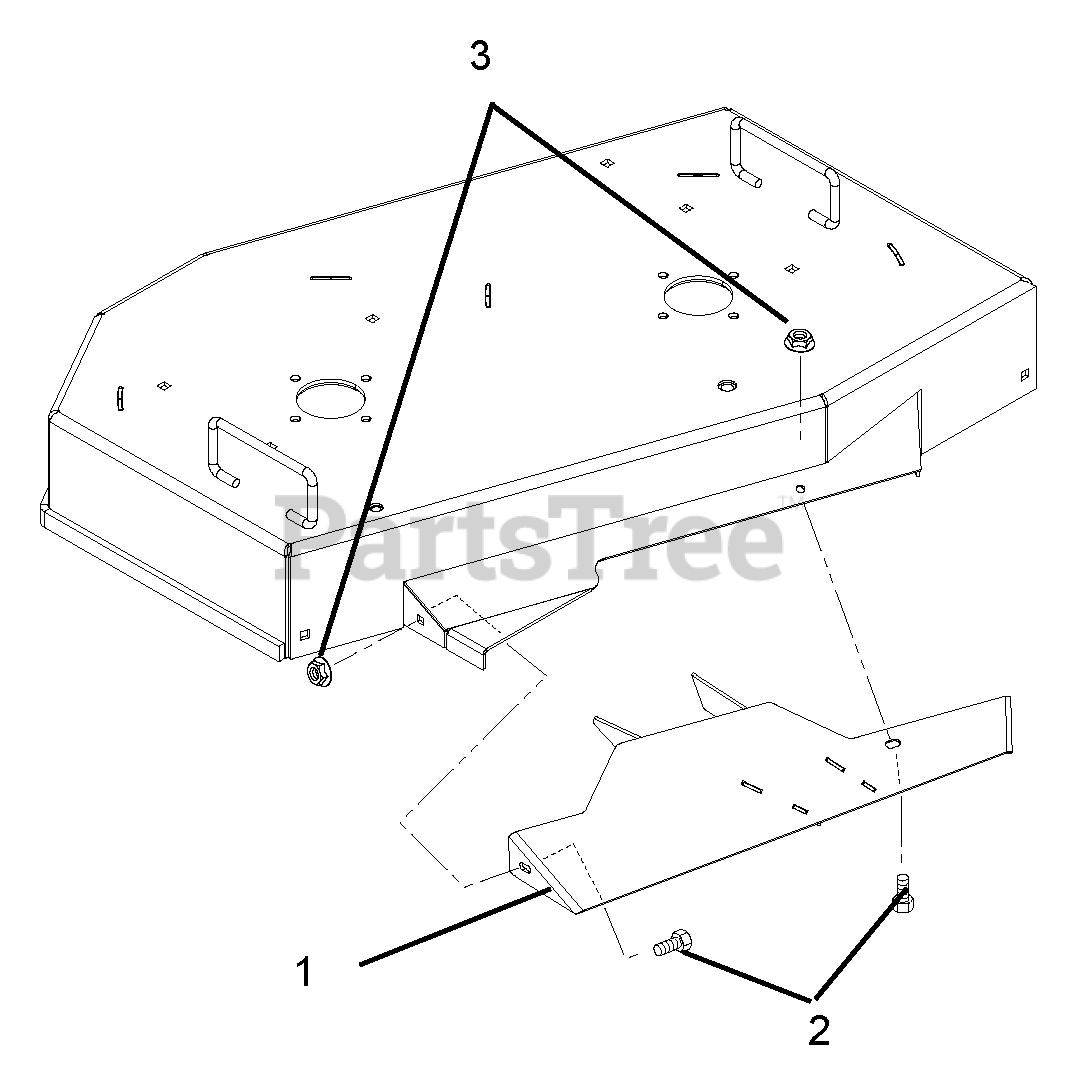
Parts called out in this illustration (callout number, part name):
1	WMT-32" DEFLECT EXT-REAR DISCH
2	BRACKET, GEAR BOX MOUNTING-LH
3	@NUT-LK-TOP-FLG .31-18 YWZC
